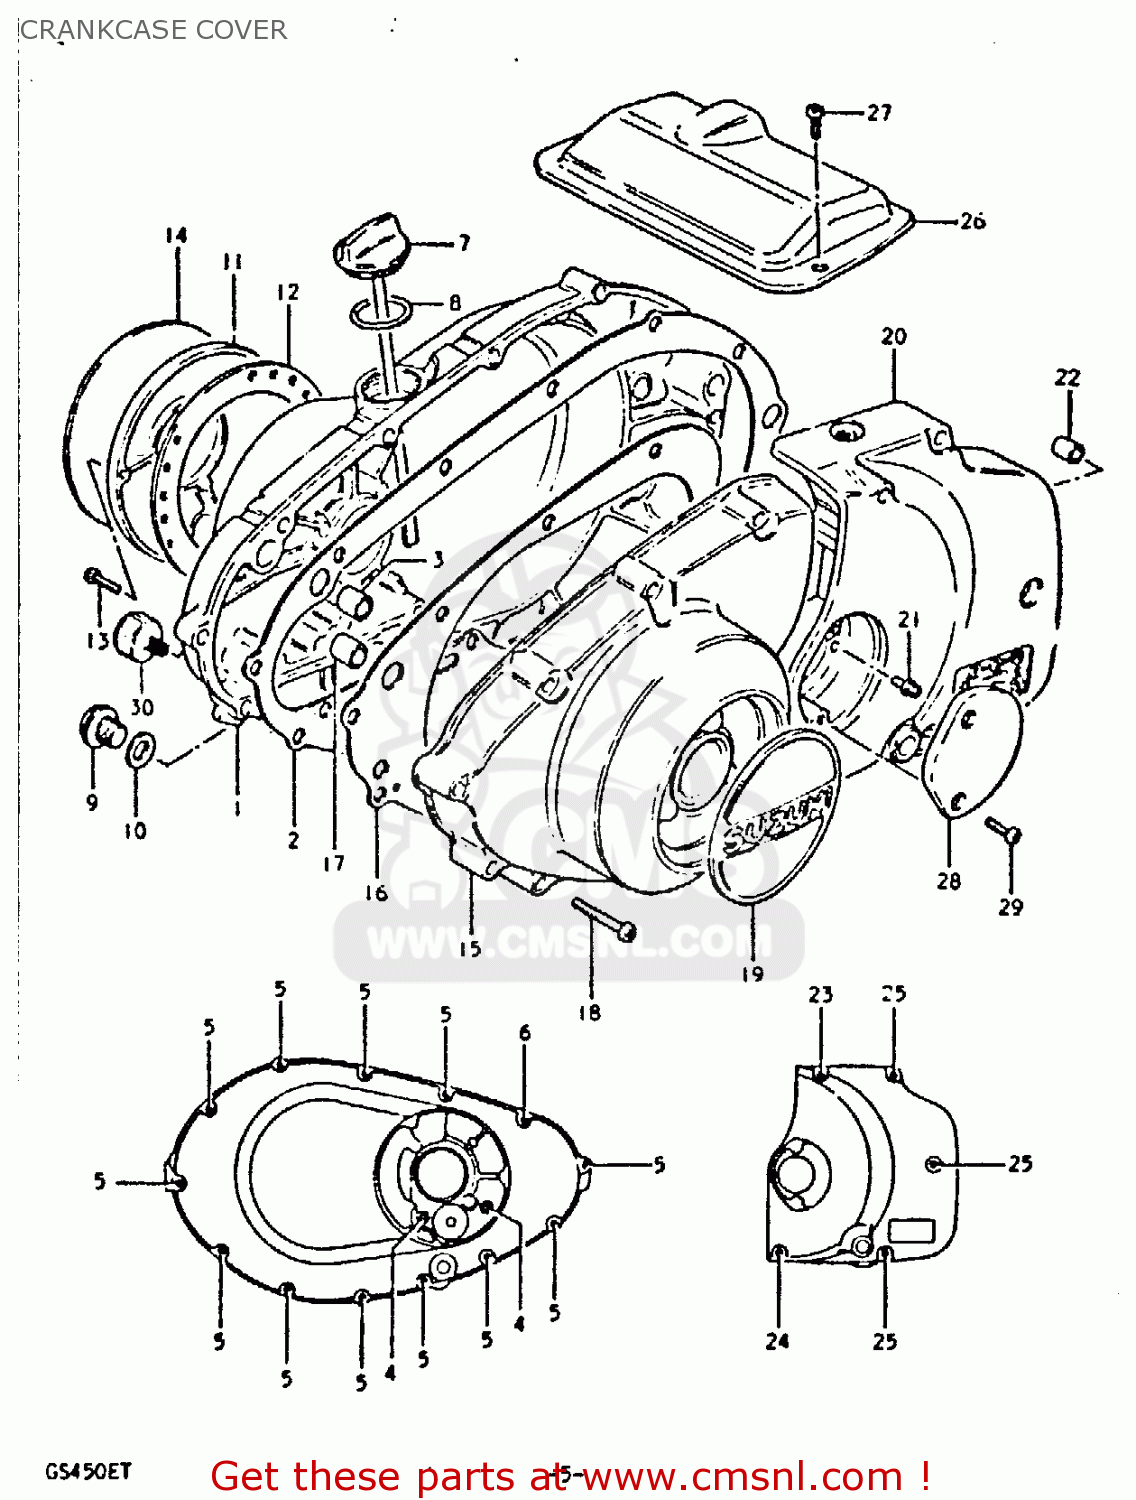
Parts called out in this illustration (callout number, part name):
1	COVER,CLUTCH
2	GASKET,CLUTCH COVER (MCA)
3	PIN
4	SCREW
5	SCREW (6X35)
6	SCREW
7	GAUGE,OIL LEVEL
8	O-RING
9	PLUG (14X12)
10	GASKET(14X19.2X2) (NAS)
11	COVER,CONTACT BREAKER
12	GASKET,CONTACT BREAKER COVER (NAS)
13	SCREW
14	EMBLEM,MAGNETO COVER
15	COVER
16	GASKET,MAGNETO COVER (MCA)
17	PIN
18	SCREW (6X35)
19	EMBLEM,MAGNETO COVER
20	COVER,SPROCKET
21	NIPPLE
22	PIN
23	SCREW 6X65
24	SCREW
25	SCREW
26	COVER,STARTER MOTOR
27	SCREW
28	CAP,CLUTCH RELEASE ADJUST
29	SCREW
30	SWITCH ASSEMBLY
